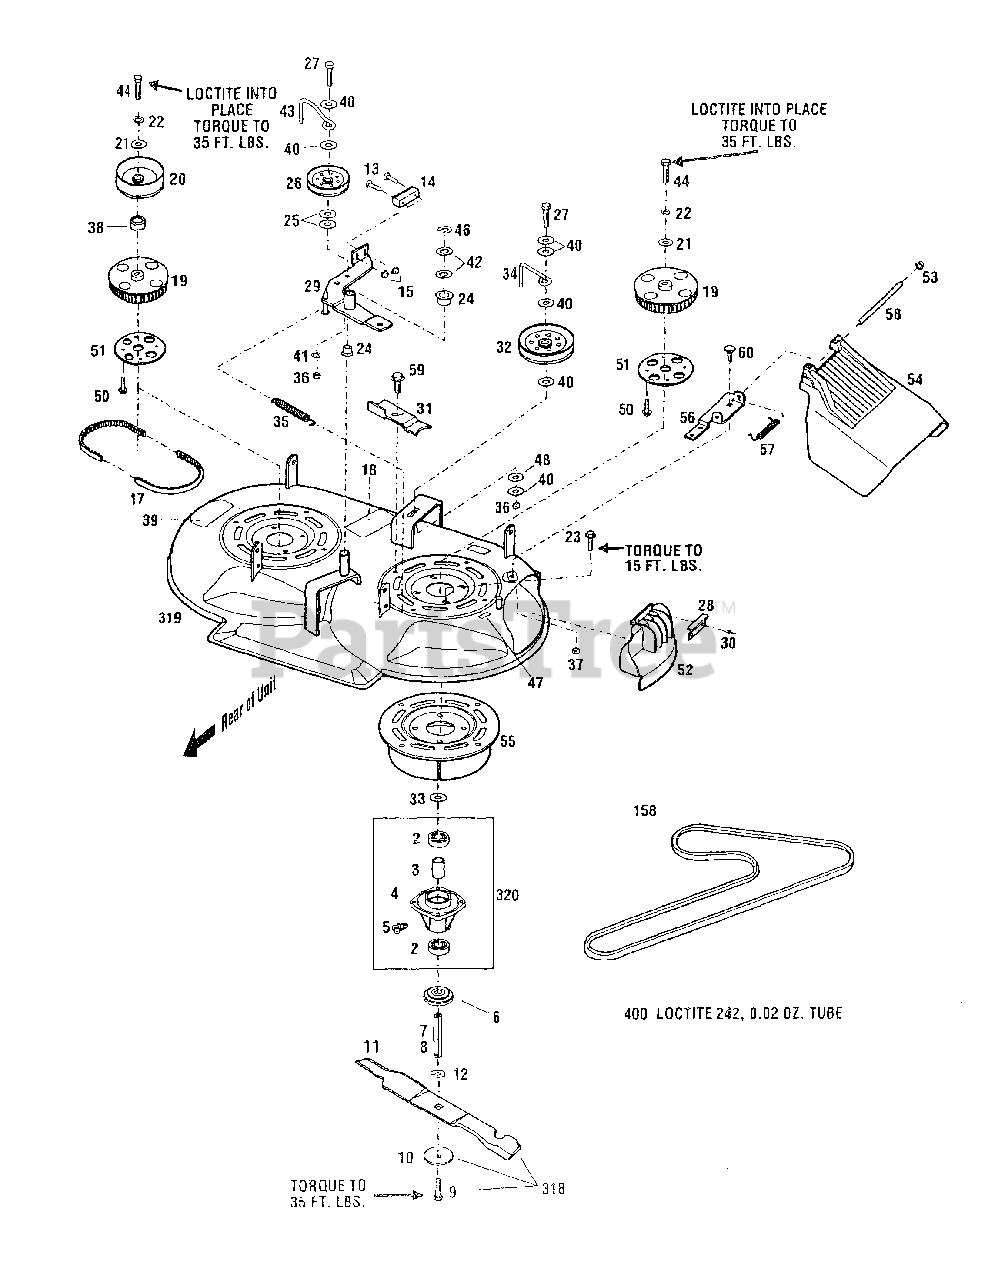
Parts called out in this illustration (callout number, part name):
2	Ball Bearing
4	Mower Spindle
5	Grease Fitting
6	Blade Spacer
7	Right Spindle Shaft
8	Left Spindle Shaft (long)
9	Screw, 7/16-14 x 1
10	Belleville Washer
11	Blade, 33" Mulching
12	Retaining Ring
13	Flat Head Screw, #10-24 x 1-1/4
14	Brake Pad
15	Nylon Locknut, #10-24
17	Toothed Drive Belt
18	Caution Decal
19	Cogged Pulley, 56T
20	Drive Pulley
21	Flat Washer, 7/16
22	Lock Washer, 7/16
23	Flange Lock Screw, 5/16-18 x 1
24	Range Bushing
25	Flat Washer
26	Idler Pulley
27	Hex Head Capscrew, 3/8-16 x 2-1/2
28	Adapter Trim
29	Idler Arm
30	Pop Rivet
31	Belt Tension Adjustment Bracket
32	Idler Pulley
33	Special Thrust Washer
34	Belt Guide
35	Extension Spring
36	Nut, 3/8-16
37	Locknut, 5/16-18
38	Pulley Spacer
39	Danger Decal
40	Flat Washer, 3/8 x 3/4
41	Lock Washer, 3/8
42	Flat Washer
43	Belt Guide
44	Screw, 7/16-14 x 1-1/4
46	Retaining Ring
47	Warning Decal
48	Pyramid Washer, 3/8
50	Triplask Screw, 1/4-20 x 5/8
51	Sprocket Plate
52	Mulcher Cover, Fold-Up Style
53	Cap
54	Discharge Chute
55	Weldment Doubler
56	Bracket, Chute Hinge
57	Spring, Discharge Chute
58	Pin, Discharge Chute
59	Screw, Thread-Forming
60	Bolt, Carriage, 3/8-18 x 3/4
318	Mulching Blade Kit
319	Mower Deck Assembly
320	Mower Spindle Assembly
400	Loctite 242, 0.02 oz.
